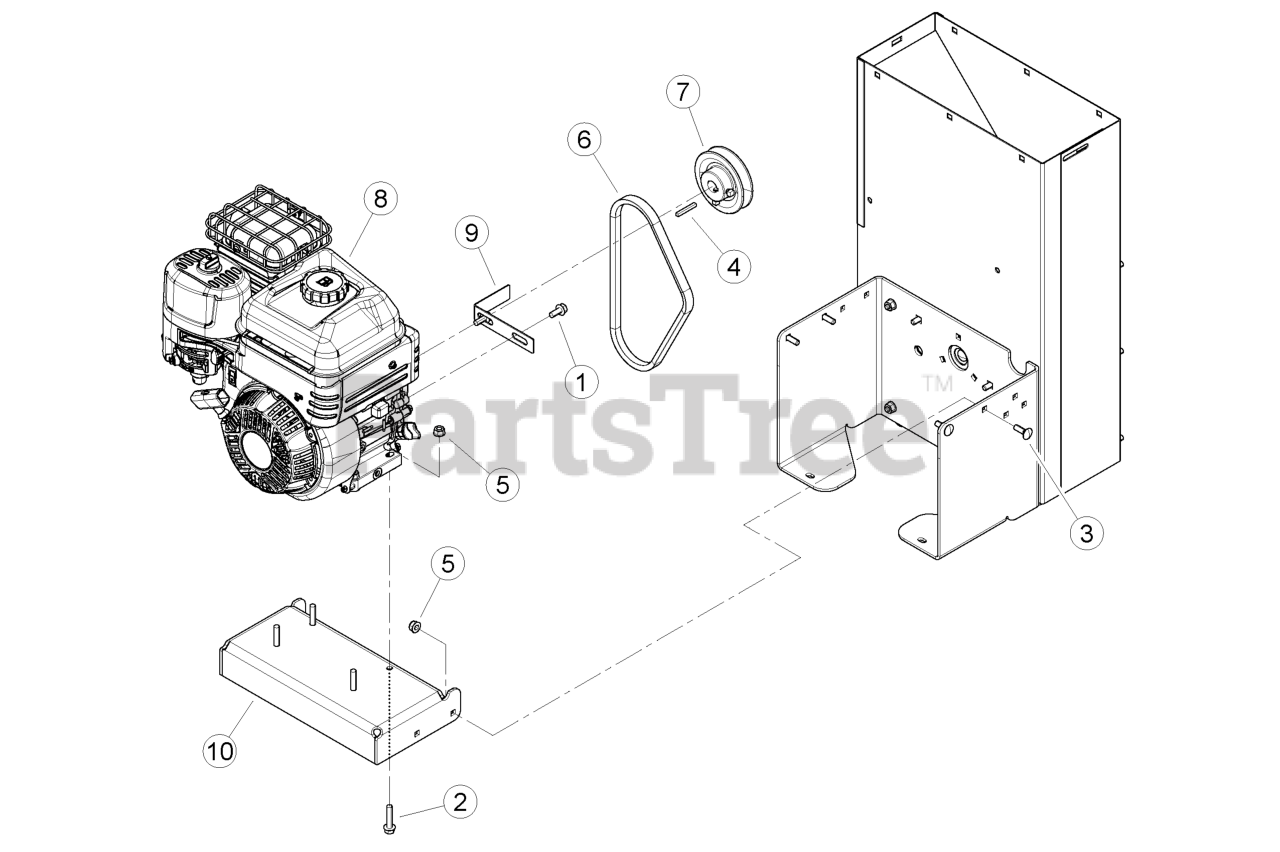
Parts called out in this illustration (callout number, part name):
1	BOLT, 5/16 × 3/4 SERRATED FLANGE NF
2	BOLT, 5/16 × 1-1/2 FLANGE NC
3	BOLT, 5/16-18 × 1 GR5 CRG
4	KEY, SQUARE 3/16" × 1-1/2" LG PLN
5	NUT, 5/16-18 NYLOCK FLANGE
6	BELT, 29" C/S
7	PULLEY, CAST 4" OD 3/4" BORE B GR
8	ENGINE, 208cc 900 SERIES B&S
9	GUIDE, BELT
10	PLATE, ENGINE MOUNTING
